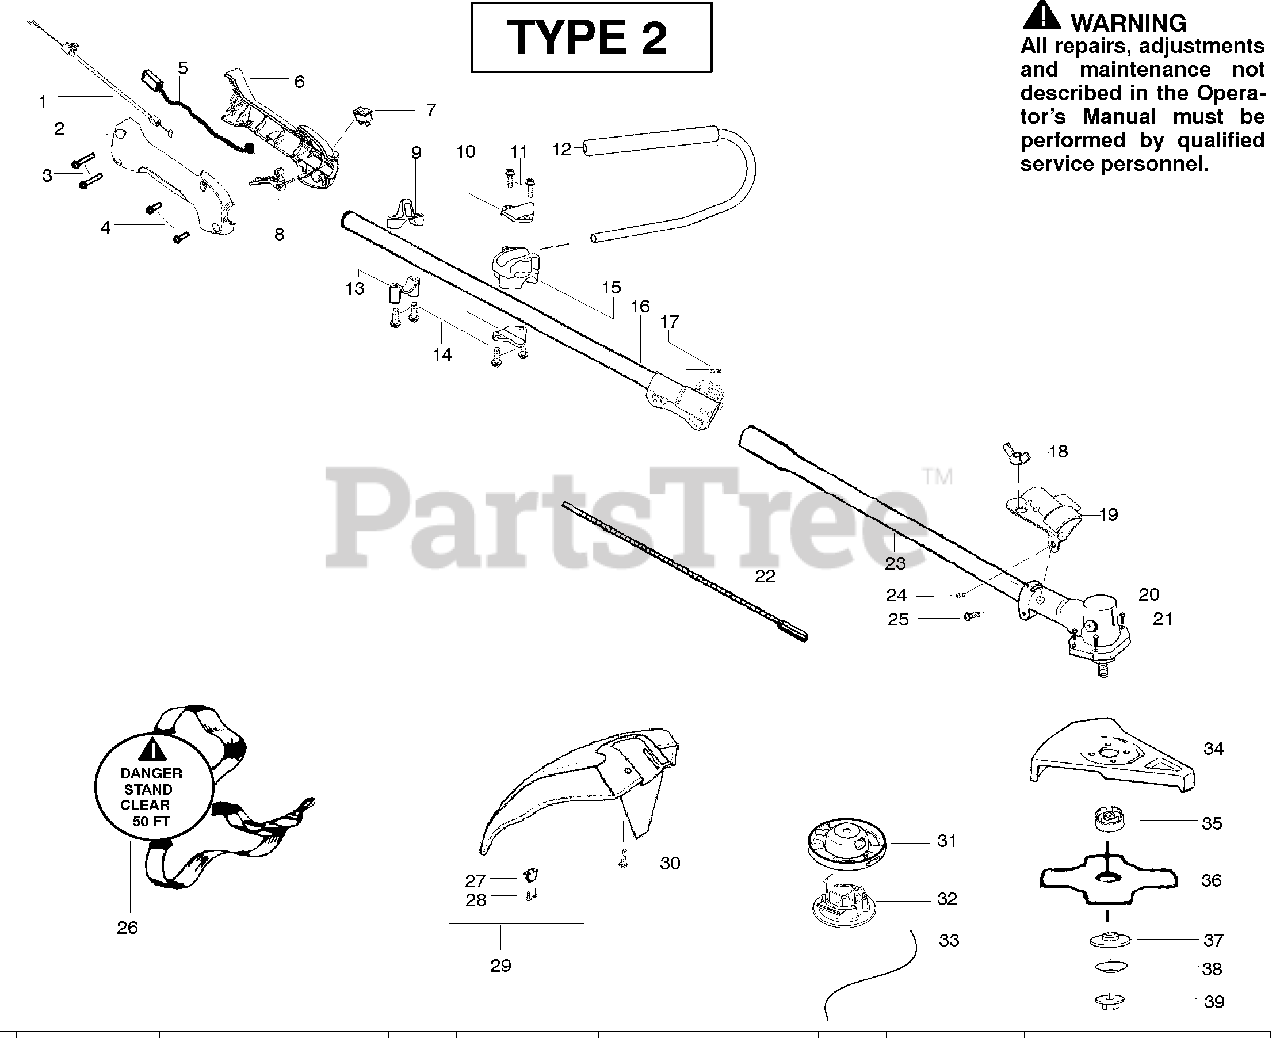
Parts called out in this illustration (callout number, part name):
1	Assy-Throttle Cable
2	Hsg-Throttle-right
6	Hsg-Throttle-left
7	Kit-Switch
8	Trigger-Throttle
9	Clamp-Harness (upper)
10	Clamp-Bracket
12	Assy-Handlebar
13	Clamp-Harness (lower)
15	Clamp-Handlebar
16	Kit-Upper Shaft
18	Wingnut
19	Bracket-Shield
22	Shaft-Flex (lower)
23	Assy-Lower Shaft
26	Shoulder Strap
29	Kit-Shield Assy
31	Head-Fixed line
32	Cap-Fixed Line
33	Accy-Line (12 pcs)
34	Kit-Metal Shield
36	Accy-Weed Blade
38	Washer-Belleville
